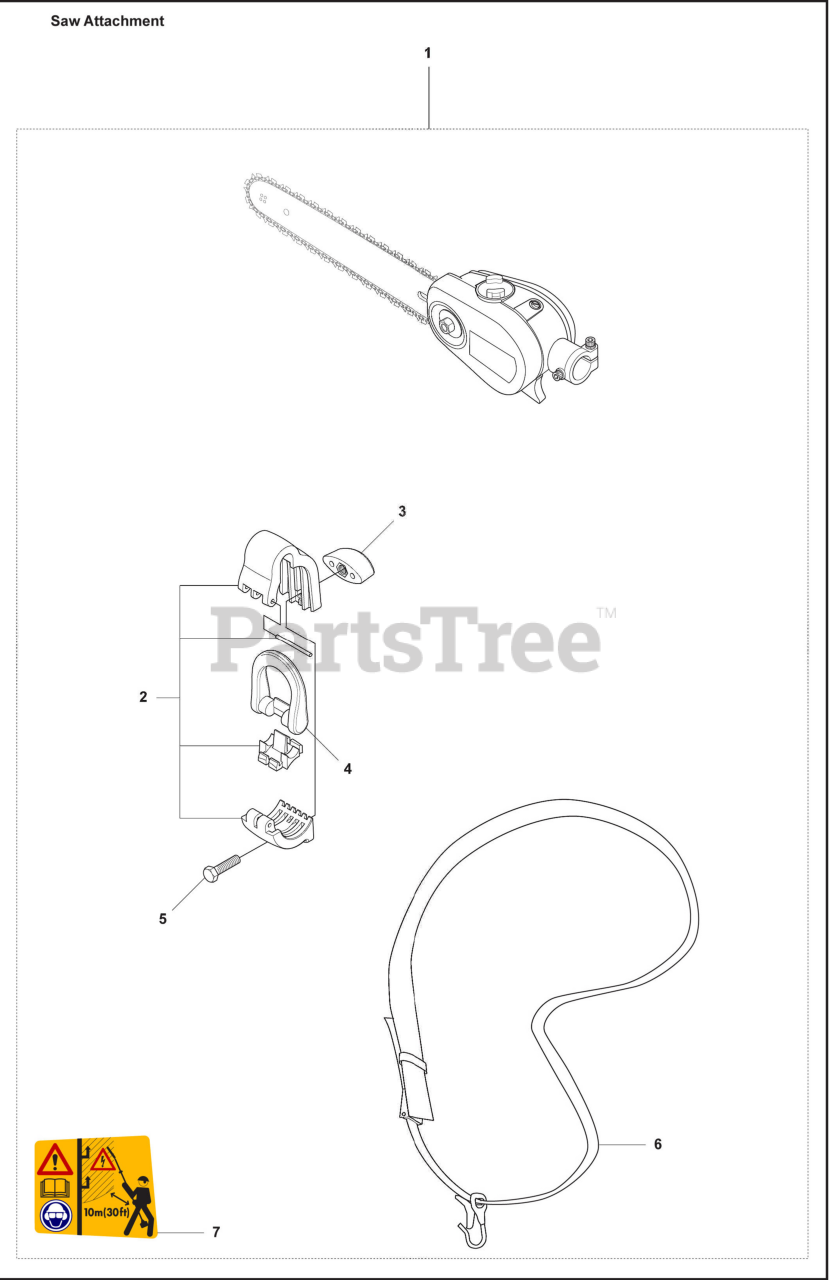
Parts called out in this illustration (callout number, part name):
1	POLE SAW HEAD 12 IN
1	Pole Saw Head W/12" Bar &
2	Hanging Bracket
5	Screw, M6S 5 X 20
6	Shoulder Strap with Sign
7	Decal
